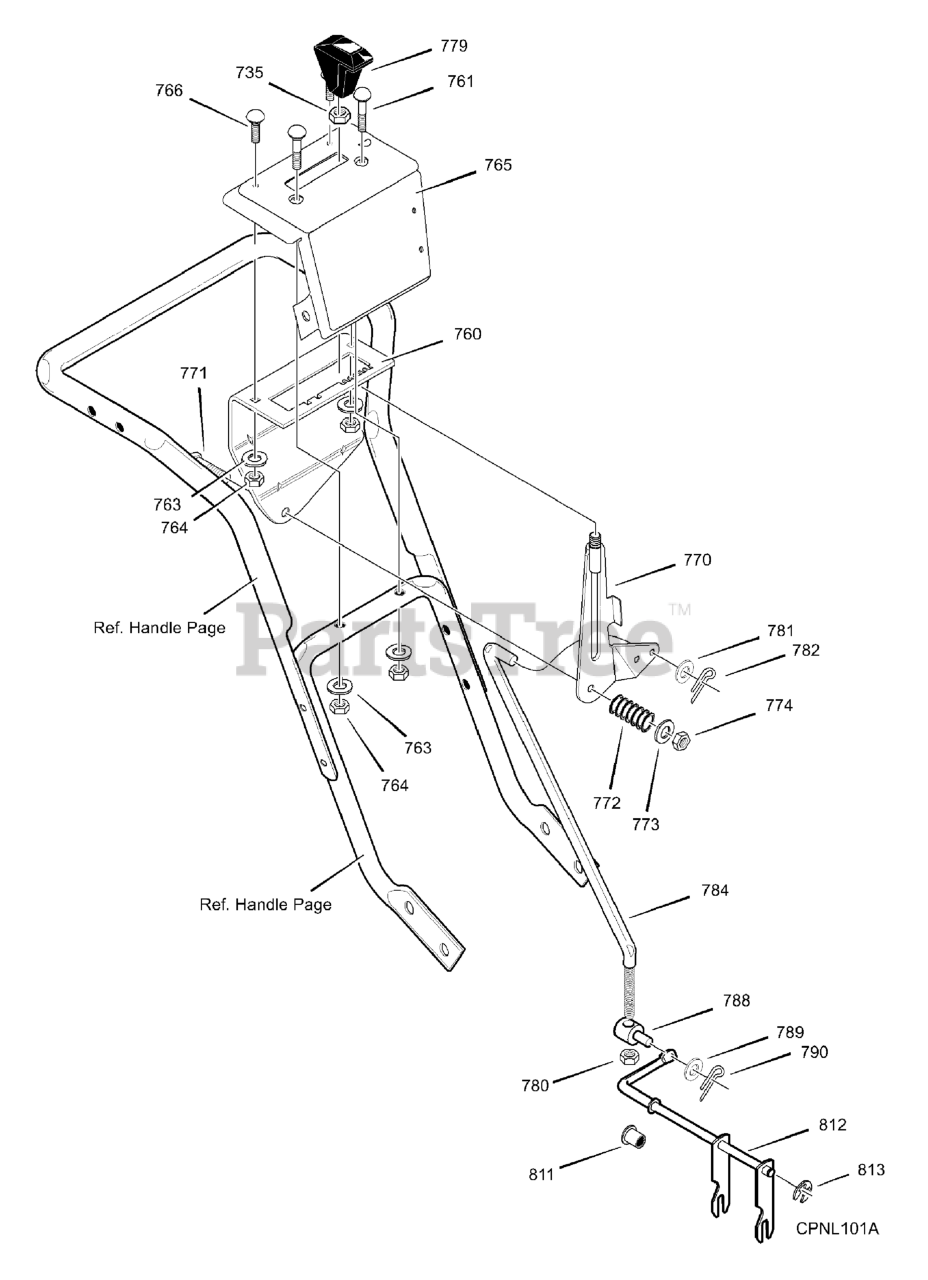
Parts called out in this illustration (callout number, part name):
735	NUT, 3/8-16 HEXJAM
760	BRACKET, SHIFT CONTROL
761	CARR. BOLT, 1/4-20 X 2
763	WASHER, HVSPTLK
764	NUT, 1/4-20 REGHEX
765	CONTROL PANEL
766	CARR. BOLT, 1/4-20 X 0.63
770	SHIFT LEVER ASSY
771	SCREW, 5/16-18 x 1.75
773	FLATWASHER
774	NUT, 5/16-18 HEXNYL
779	KNOB, SHIFT
780	NUT, 5/16-24
781	WASHER, FLAT .349X.69X.066
782	PIN, COTTER
784	ROD, SPEED CONTROL
788	NUT, TRUNNION 5/16-24
789	WASHER, FLAT .349X.69X.066
790	PIN, COTTER
811	FLANGED BEARING
812	ROD ASSY, YOKE PANEL
813	RING, RETAINER
